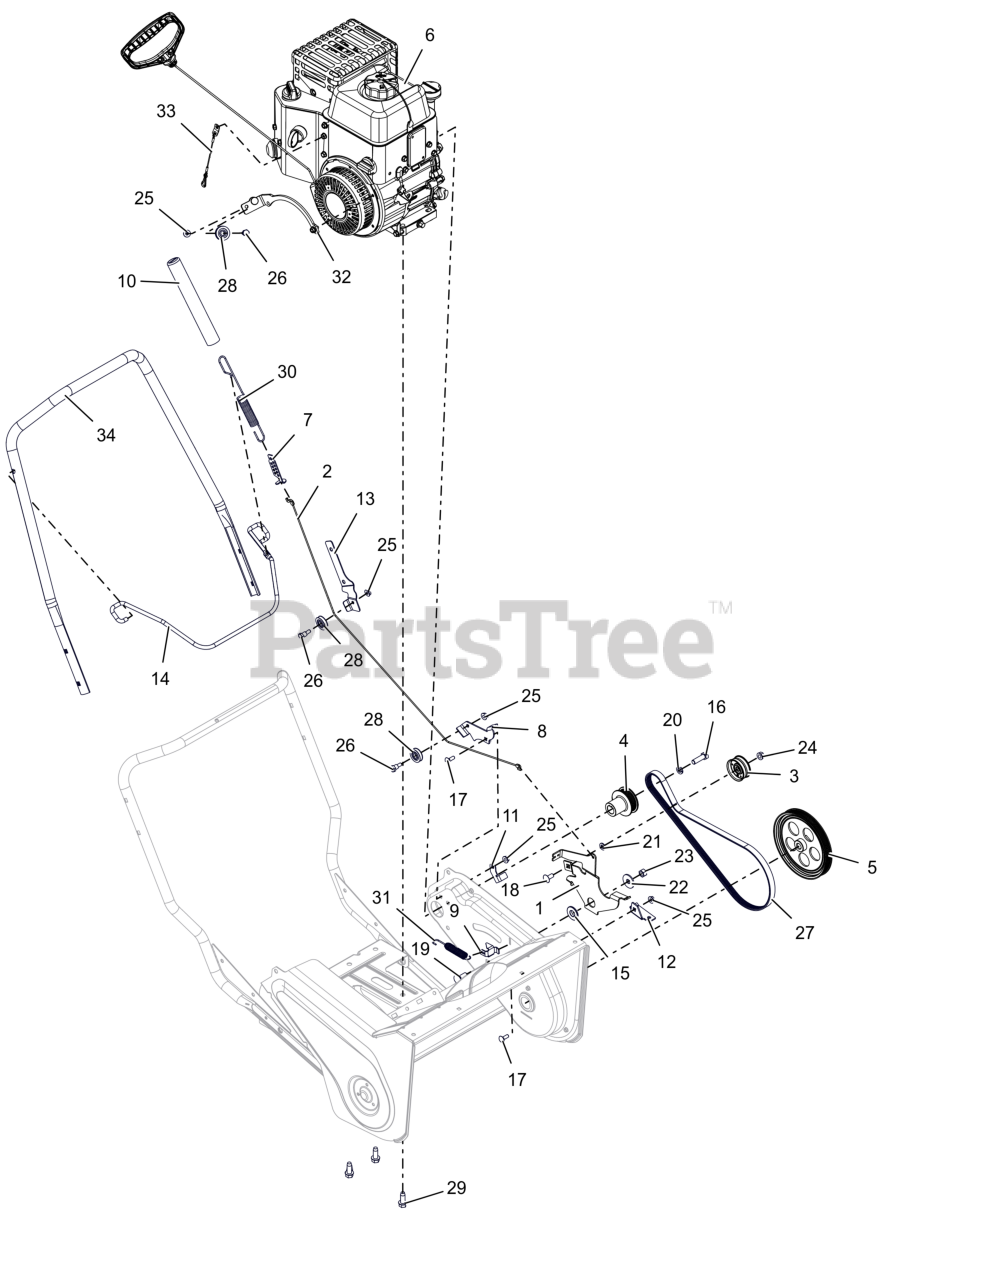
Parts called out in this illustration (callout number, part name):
1	ARM, IDLER /BRAKE
2	CABLE, AUGER
3	IDLER, FLAT - 1.875"
4	SHEAVE, ENGINE - 6J
5	PULLEY, POLY V-BELT J-6 W/HUB
6	ENGINE, AX208 LW RECOIL ASM
7	PLATE, CABLE ADJUSTMENT
8	BRKT, CABLE PULLEY
9	BRKT, SPRG
10	COVER, CABLE SPRING
11	FINGER, BELT
12	FINGER, BELT
13	MOUNT, CABLE PULLEY (ORANGE)
14	BAIL, AUGER (BLACK)
15	BSHG-FLG .555X.860X.220X1.250
16	BLT, HEX .38-24X1.25 G5 ZCC
17	BLT, RHSN .25-20X.750 G5 ZCC
18	BLT, RHSSN.31-18X.750 G5 ZCC
19	BLT, RHSN .38-16X1.00 G5 ZCC
20	WSHR,LK-REG .375X.094 ZCC
21	WSHR,FLT .323X.625X.062 ZCC
22	WSHR FL STL .406X1.25X.10ZC120
23	NUT-LK-CTR .38-16 ZC120
24	NUT,LK-CTR-FLG .31-18 GF ZCC
25	NUT-LK-TOP-FLG .250-20 GF ZCC
26	BOLT, SHLDR -.375 X .375 X .25-20
27	POLY V-BELT, J-6 RIBS
28	PULLEY, CABLE
29	SCR-TAP .38-16X1.00 HWH TR ZCC
30	SPRG, EXT .100X.740X8.175
31	SPRING, EXTENSION-SWIVEL
32	RECOIL ROLLER WELDMENT BRACKET
33	LANYARD, TAB AND CLIP - 5"
34	HANDLEBAR, UPPPER - W/DECAL
